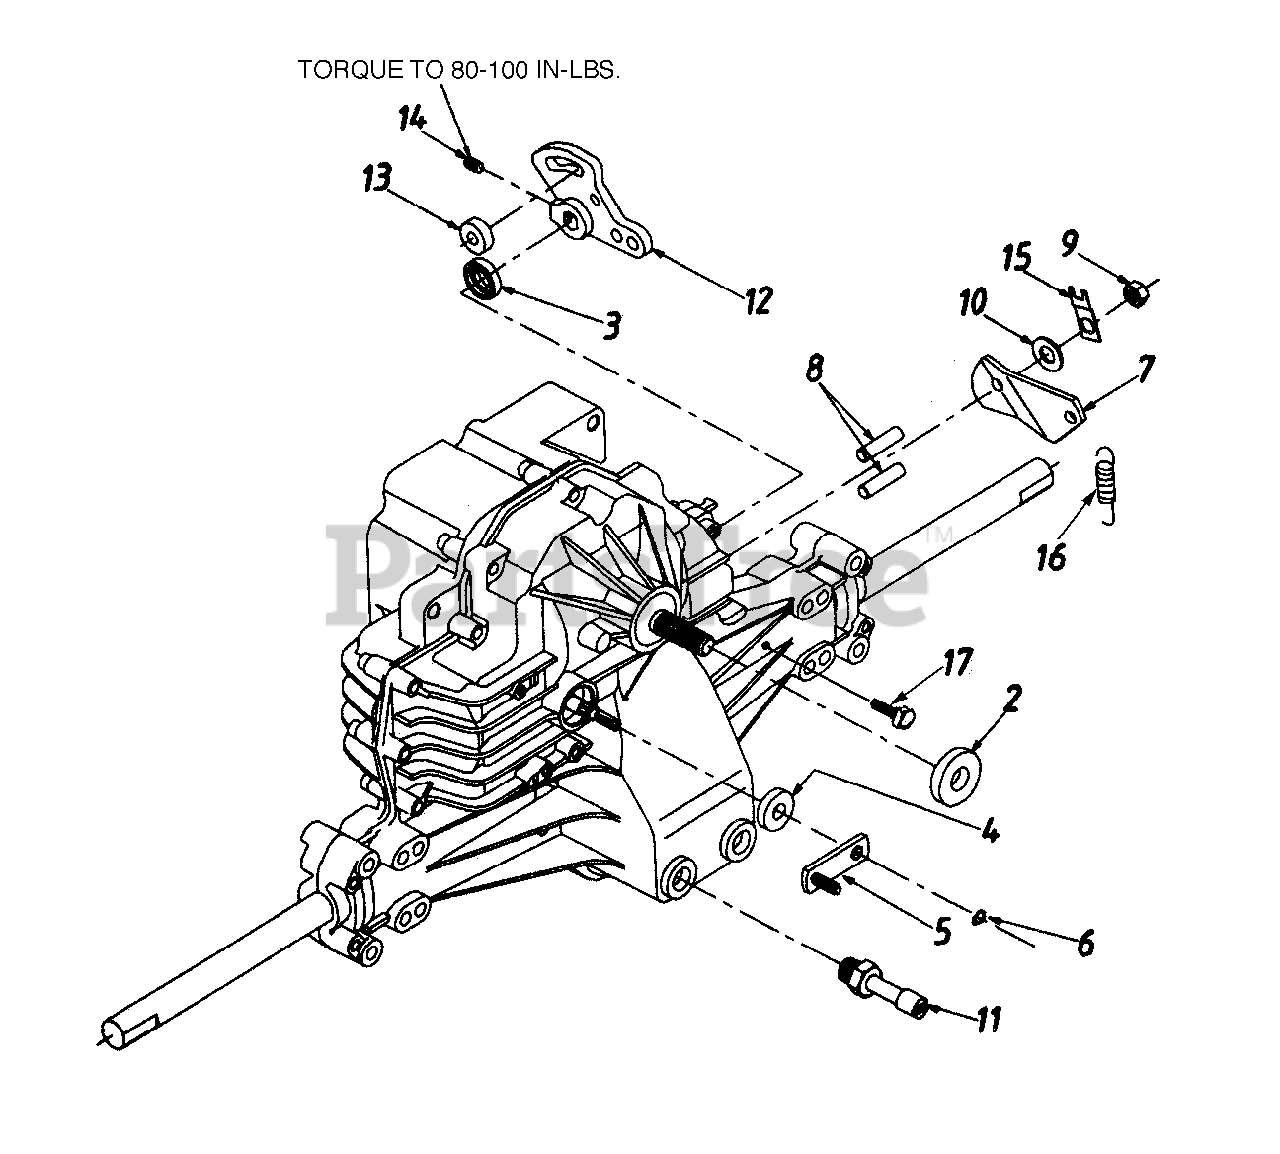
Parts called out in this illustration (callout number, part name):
4	Seal-Lip 10x 25X7
5	Arm-Bypass
6	Ring-Retaining
7	Arm-Actuating
8	Pin-Actuating
9	Nut-Hex Lock 5/16-24
10	Washer 7/16" x 7/8" x .06"
11	Breather Ass'y.
12	Arm-Control
13	Puck-Dampener
14	Set Screw
15	Strap, Locking
16	Ext. Spring
17	Self Tapping Scr. #10-32
